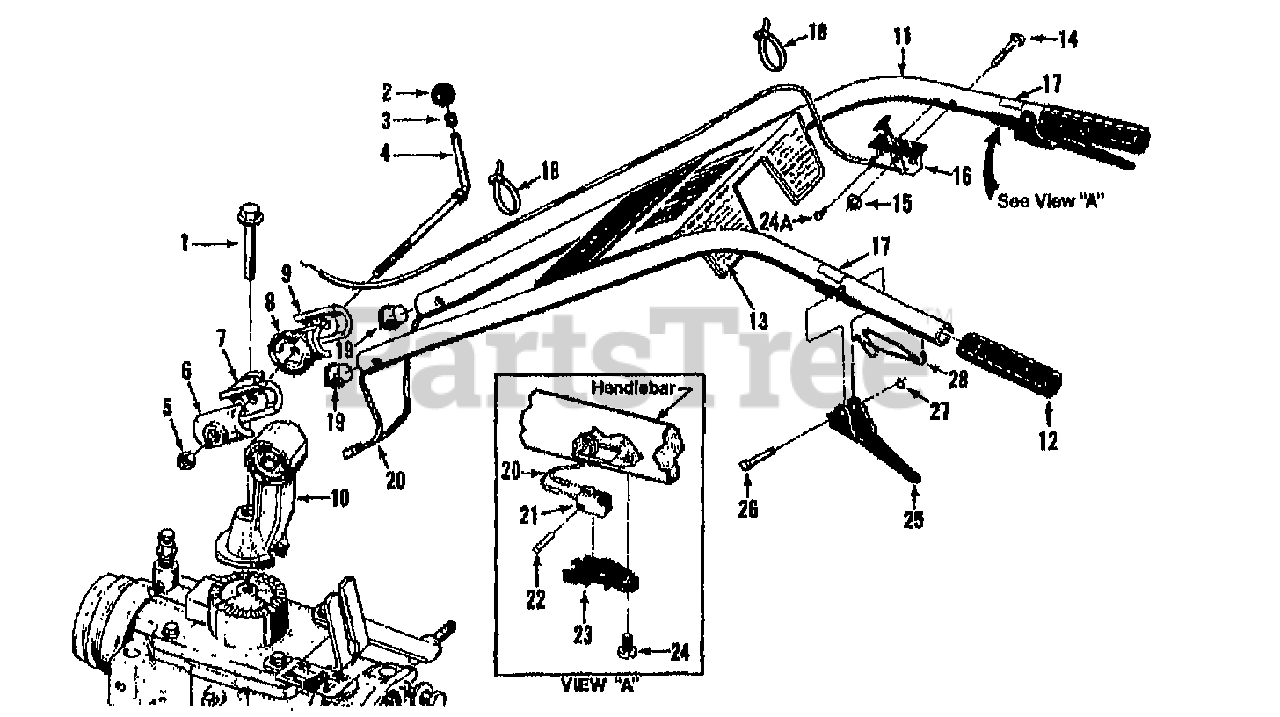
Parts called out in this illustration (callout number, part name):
1	BOLT 1/2-13X3.5 FH GR5
2	KNOB-CONTROL (INCL. 3)
3	RING-TOLERANCE .5325 ID
4	STUD-H/BAR W/NUT & RING (INCL. 2,3 & 5)
5	NUT-HEX JAM 1/2-13
6	CLAMP-LH HORSE 1021-1
7	RATCHET-H/BAR RED 2542-1
8	RATCHET-RH RED HORSE 2542-2
9	CLAMP-RH HORSE 1021-2
10	BASE-H/BAR RED 2534A
11	ASSM-HANDLEBAR W/GRIPS (INCL. 2 OF EA. 12, 17 & 28 AND ONE 13)
12	GRIP-H/BAR SMOOTH
13	DECAL-CONTROL PANEL HORSE
13	DECAL-CONTROL PANEL (11HP)
14	BOLT-CH 1/4-20X2.00 ZP
15	NUT-HF/LK 1/4-20 ZP
16	CABLE-THROTTLE 7 I/C B&S {12068/069/080/081/087}
16	CABLE-THROTTLE 7&8 B&S {12074/075/088/089/090}
16	CABLE-THROTTLE 8HP OPC {12070/071/082/083}
17	DECAL-FWD INTERLOCK
18	TIE-RED
19	RETAINER-HARNESS H/B OPC
20	HARNESS-WIRE OPC HORSE
21	SWITCH-H/B OPC
22	PIN-LK .11X.58 HORSE OPC
23	HOUSING-SWITCH OPC
24	SCR-HW M10-24X.5 STH ZP
24A	SCR-PHS M10-32X.5 STH ZP
25	LEVER-HORSE OPC
26	PIN-PIVOT OPC LEVER
27	RING-KLIP 5304-25
28	SPRING-H/B LEVER
